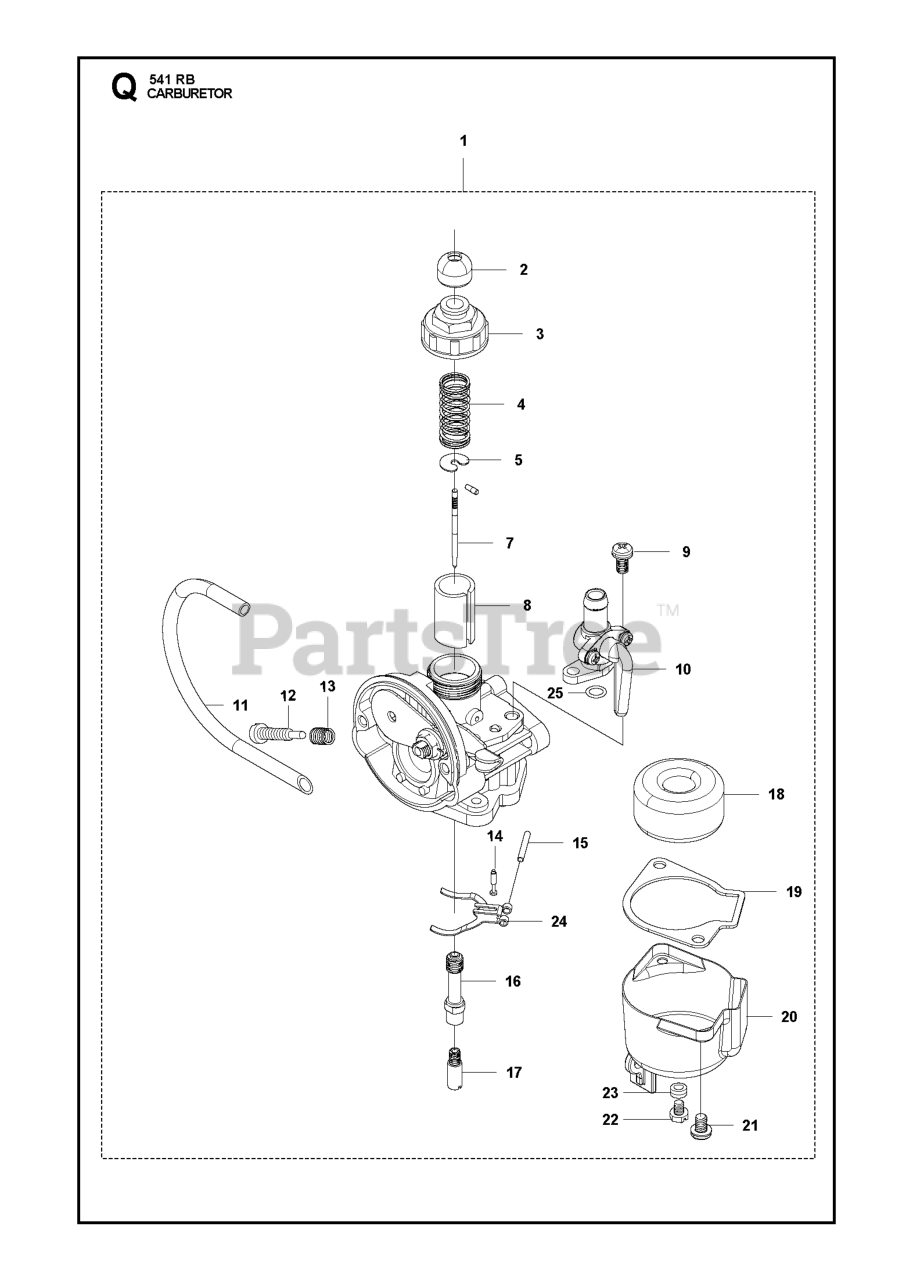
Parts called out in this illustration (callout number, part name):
4	SPRING.THROTTLE
8	VALVE.THROTTLE
12	SCREW.ADJUST
14	VALVE.NEEDLE
